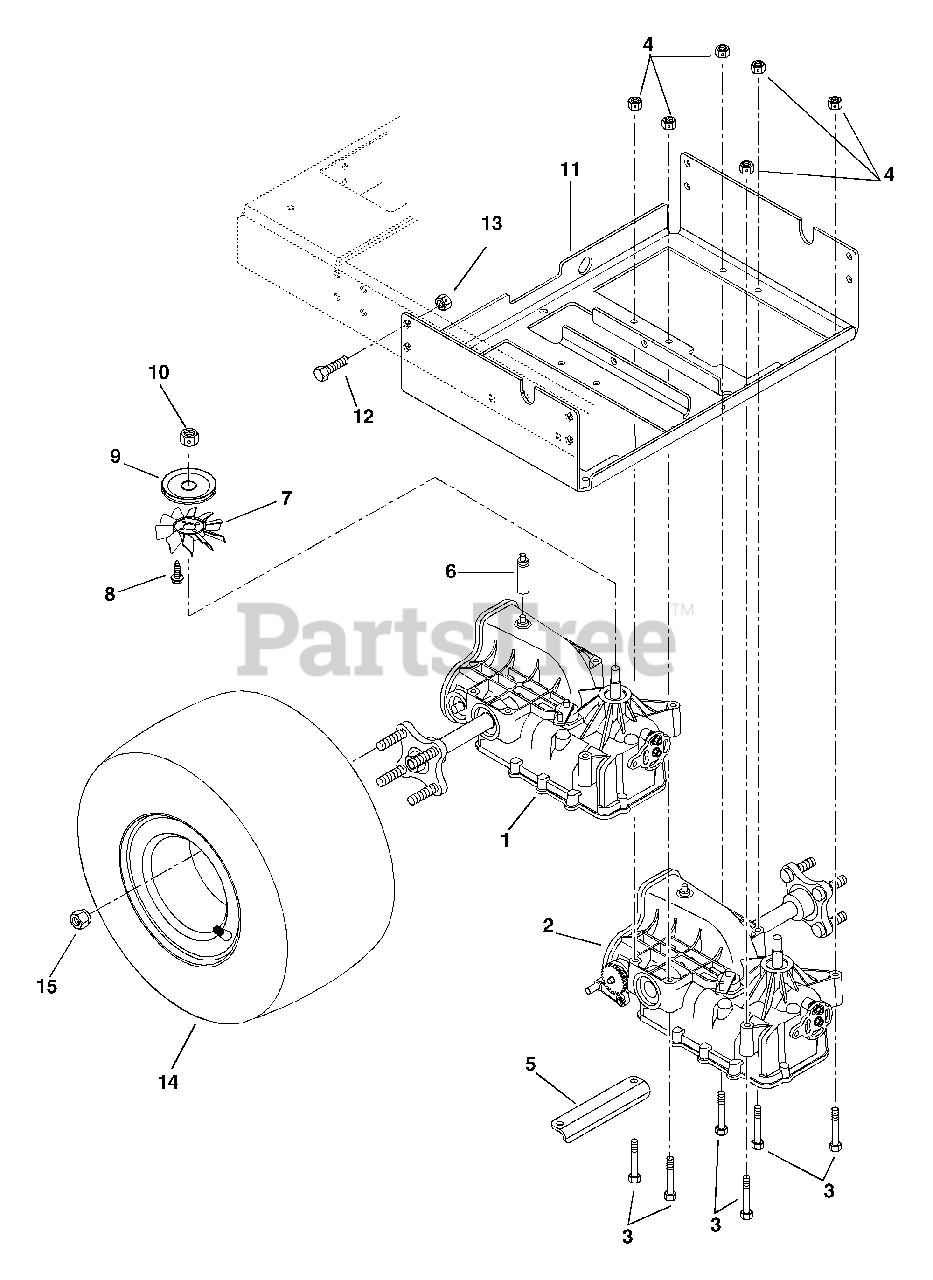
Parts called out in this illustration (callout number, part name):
1	Transaxle Hydro-Gear Right Hand
2	Transaxle Hydro-Gear Left Hand
3	Bolt-Hex .31-18 x 2.50 Grade 5
4	Nut-Locking-Center .31-18
5	Transaxle Bracket
6	Hose-Vent
7	Fan
8	Screw-Tapping 10-24 x .75 Hex Washer Head
9	Sheave - Transaxle
10	Nut-Locking-Center .50-20
11	Transmission Cradle
12	Bolt-Hex .38-16 x .75 Grade 5
13	Nut-Locking-Center .38-16
14	Tire/Wheel 18 x 8.50-8
14	Rim for 18 x 8.50-8 Tire
14	Tire 18 x 8.50-8
15	Nut-Lug .50-20
